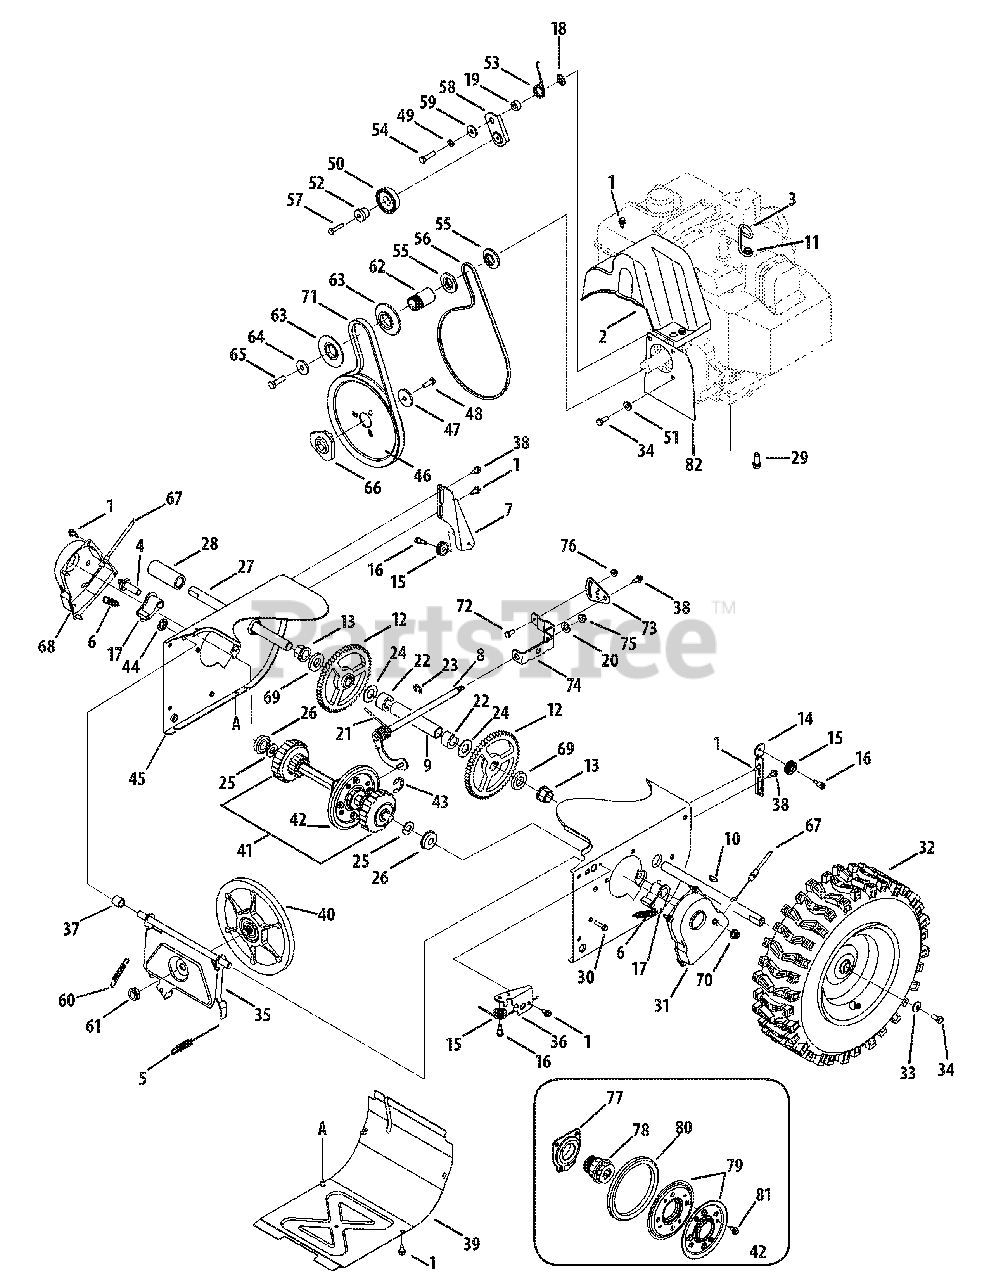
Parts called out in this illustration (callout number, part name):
1	AB Screw, 1/4-20 x 0.625
2	Belt Cover
3	Cable Guide
4	Actuator Shaft
5	Drive Clutch Cable
6	Extension Spring
8	Shift Rod Assembly
9	Axle Support Tube
10	Hi-pro Key
11	TT Screw, 5/16-18 x 1.00
12	Gear, 56T
13	Hex Flange Bearing
15	Cable Roller
16	C Screw, 1/4-28 x 0.375
17	Dogg Assembly - LH
17	Dogg Assembly - RH
19	Spacer
20	Shift Bracket Spacer
21	Torsion Spring, .750ID x .968 Lg.
23	E Ring
24	Flat Washer, .76 x 1.49 x .06
25	Flat Washer
26	Ball Bearing
27	Axle
29	TT Sems Screw, 3/8-16 x 1.0
30	TT Screw, 1/4-20 x 1.0
33	Bell Washer
34	Hex Bolt, 5/16-24 x 0.75
38	Shoulder Screw
40	Friction Wheel Disc Assembly
41	Drive Shaft Assembly
42	Friction Wheel Assembly
43	Retainer Ring
44	Speed Nut
46	Auger Pulley
47	Flat Washer
48	Hex Bolt, 5/16-24 x 0.875
49	Lock Washer
50	Pulley Assembly
51	Shoulder Spacer
53	Torsion Spring
54	Hex Screw, 5/16-24 x 1.25
55	Pulley Half
56	V-Belt, / x 34
57	TT Screw, 1/4-20 x 1.25
58	Drive Clutch Idler Bracket
59	Shoulder Spacer
60	Extension Spring
61	Jam Lock Nut, 5/8-18
63	Pulley Half
64	Flat Washer
65	Hex Bolt, 3/8-24 x 1.25
66	Pulley Adapter
67	Steering Cable
69	Axle Spacer
70	Flange Lock Nut, 3/8-16
71	V-Belt,.500 x 35.00 Lg
72	Hex Screw, 1/4-20 x .620
75	Flange Lock Nut, 5/16-18
76	Flange Lock Nut, 1/4-20
77	Friction Wheel Bearing Assembly
78	Friction Wheel Hub
79	Friction Wheel Plate
80	Friction Wheel Rubber
